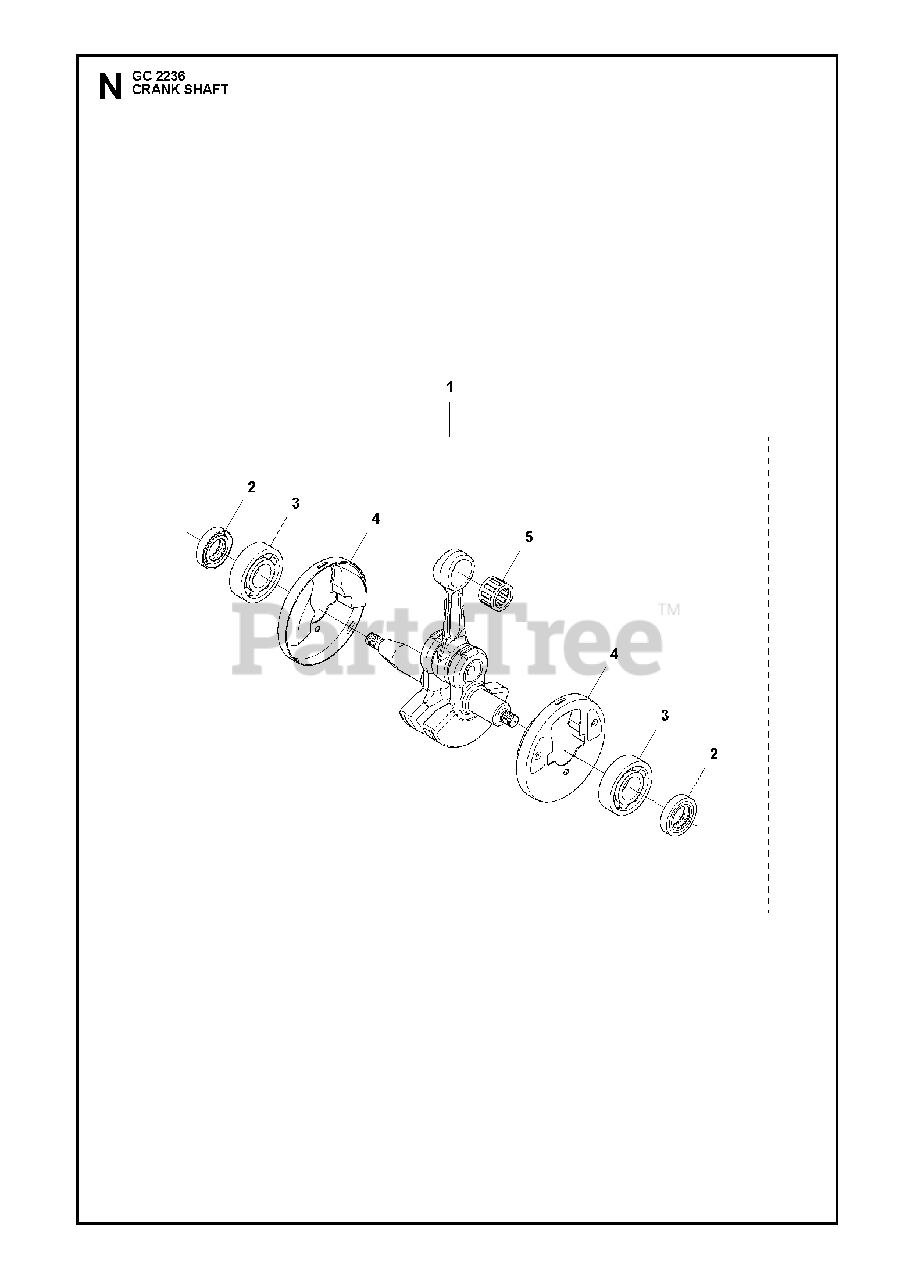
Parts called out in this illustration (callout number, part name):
1	CRANKSHAFT
2	SEALING RING
3	BALL BEARING
4	COLLAR
5	SUPPORT BUSHING
